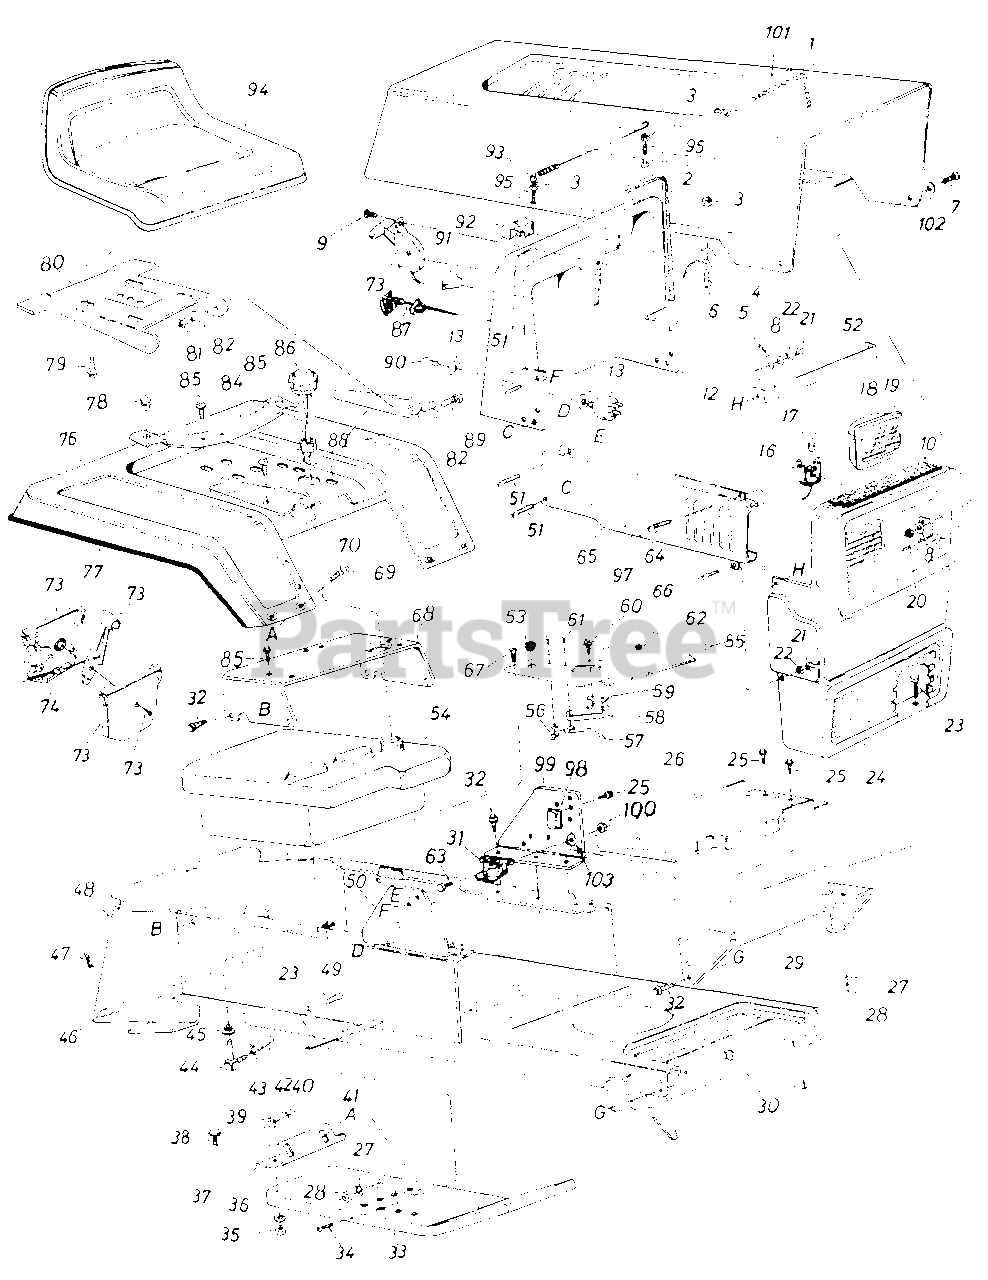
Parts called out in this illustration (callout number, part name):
1	Hood
2	Trim Strip-27" Lg.
3	Hex Sems Nut #10-24 Thd.
4	Fl-Wash. .20" I.D. x .41"
5	Hood Stop
6	Truss Hd. Mach. Scr. #10-24 x .50" Lg.
7	Shld. Bolt .375 Dia. x .125
8	Fl-Wash. 1/4" I.D.
9	Truss Mach. AB-Tap Scr. #10 x .50" Lg.
10	Foam Strip 3/8" x 1" x 14"
12	Dash Ass'y.
13	Ignition Switch
16	Socket
17	Lamp
18	Headlight Housing
19	Lens
20	L-Nut 1/4-28 Thd.
21	Hex Nut 1/4-20 Thd.
22	L-Wash. 1/4" I.D.
23	Hex Bolt 5/16-18 x .75" Lg.
24	Grille
25	Hex Wash. Hd. Scr. 1/4" x .50" Lg.
26	Battery Plate
27	L-Wash. 5/16" I.D.
28	Hex Nut 5/16-18 Thd.
29	Grille Mounting Bracket
30	Lower Frame Ass'y.
31	Solenoid
32	Hex Thd. Rolling Scr. 5/16-24 x .75" Lg.
33	Running Board-R.H.
34	Truss Mach. Scr. 5/16-18 x .75" Lg.
35	Hex Nut 5/16-18 Thd.
36	Bell-Wash. .34" I.D. x .87"
39	Hex Nut 1/4-20 Thd.
40	L-Wash. 1/4" I.D.
41	Running Board Rod
42	Fuel Line 40" Lg.
43	Hose Clamp 3/8"
44	90ø Nipple
45	Bushing
46	Hitch Rod
47	Internal Cotterpin
48	Hitch Plate
49	Speed Nut
50	Dash Support Brkt.-R.H.
51	Hex Wash. Hd. Tap Scr. 1/4 X .75" Lg.
52	Tie Strap
53	Plastic Bushing
54	Fuel Tank
55	Transmission Cover Ass'y.
56	Speed Nut #10-24 U-Type
57	Shift Lever Spring
58	Switch Spring
59	Insulator Plate
60	Hex Wash. Hd. AB-Tap Scr. #18 x .50
61	Truss Mach. Scr. #10 x .50" Lg.
62	Snap Bushing
63	Hex Bolt 1/4-20 x .50" Lg.
64	Truss Hd. Scr. 1/4-20 x .75" Lg.
66	Truss Mach. Scr. 1/4-20 x .50" Lg.
67	Truss Mach. "B" Tap Scr. #10 x .50" Lg.
68	Seat Mounting Channel
69	Carriage Bolt 1/4-20 x .50" Lg.*
70	Seat Bracket-R.H.
73	Throttle Control Box Ass'y.
74	Throttle Control Wire
78	Grommet
79	Hex Wash. Hd. AB-Tap Scr. 3/8 x .75" Lg.
80	Seat Pivot Bracket
81	Hex Cent. L-Nut 5/16-18 Thd.
82	Belleville Wash. .34" I.D. x .88n O.D.
84	Seat Spring
85	Hex Wash. Hd. Self-Tap Scr. 5/16-18 x .50" Lg.
86	Gas Cap w/Gauge
87	Choke Control Comp.
88	Seat Bracket-L.H.
89	Hex Bolt 5/16-18 x .75" Lg.
90	Ignition Key
91	Light Switch
92	Ammeter
93	Hood Spring
94	Seat Ass'y.
95	Hex Screw #10-24 x 1.0" Lg.
97	Rubber Strip 1/2" Sq. x 2 l/2" Lg.
98	Circuit Breaker
99	Dash Support Brkt.-L.H.
100	Hex Sems Nut 1/4-20 Thd.
101	PVC Foam Strip
102	Washer .34" I.D. x .62"
103	External L.-Wash. 1/4" I.D.
